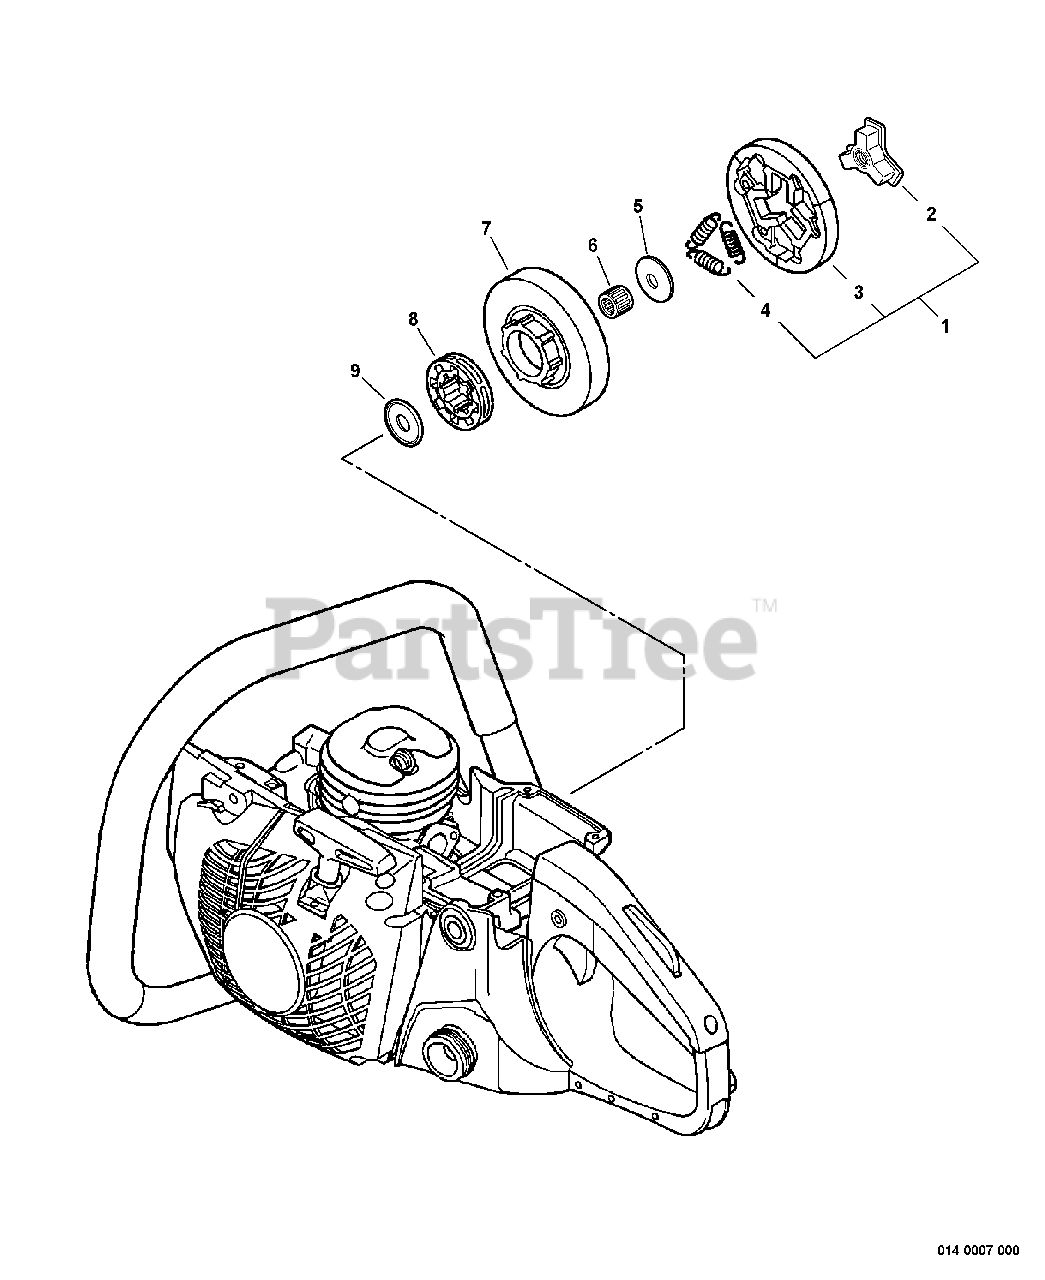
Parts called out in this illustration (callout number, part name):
1	CLUTCH ASSY
2	HUB, CLUTCH
3	CLUTCH SHOE SET
4	SPRING, CLUTCH
5	PLATE, CLUTCH
6	BEARING, NEEDLE
7	DRUM, CLUTCH
8	SPROCKET, RIM
9	PLATE, CLUTCH
